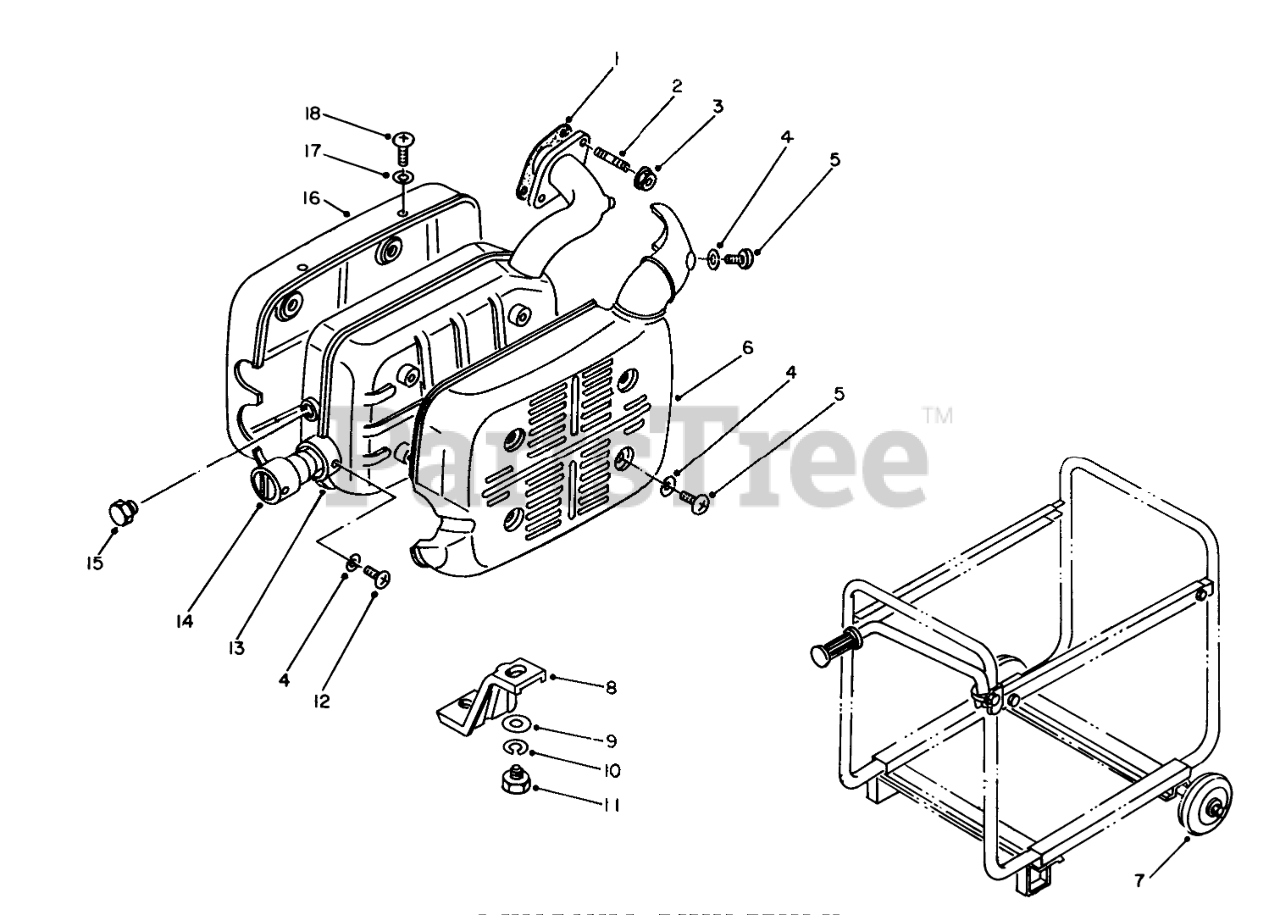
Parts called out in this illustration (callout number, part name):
1	EX GASKET
2	Stud Bolt
4	Lockwasher
5	SCREW
6	Cover-Front
7	Wheel Assembly (Optional)
8	Bracket-Muffler
9	Washer
10	WASHER-LOCK
12	Screw
13	MUFFLER ASM
14	Cleanout Tube
15	Drain Plug
16	Cover-Rear
17	Lockwasher
18	Screw
